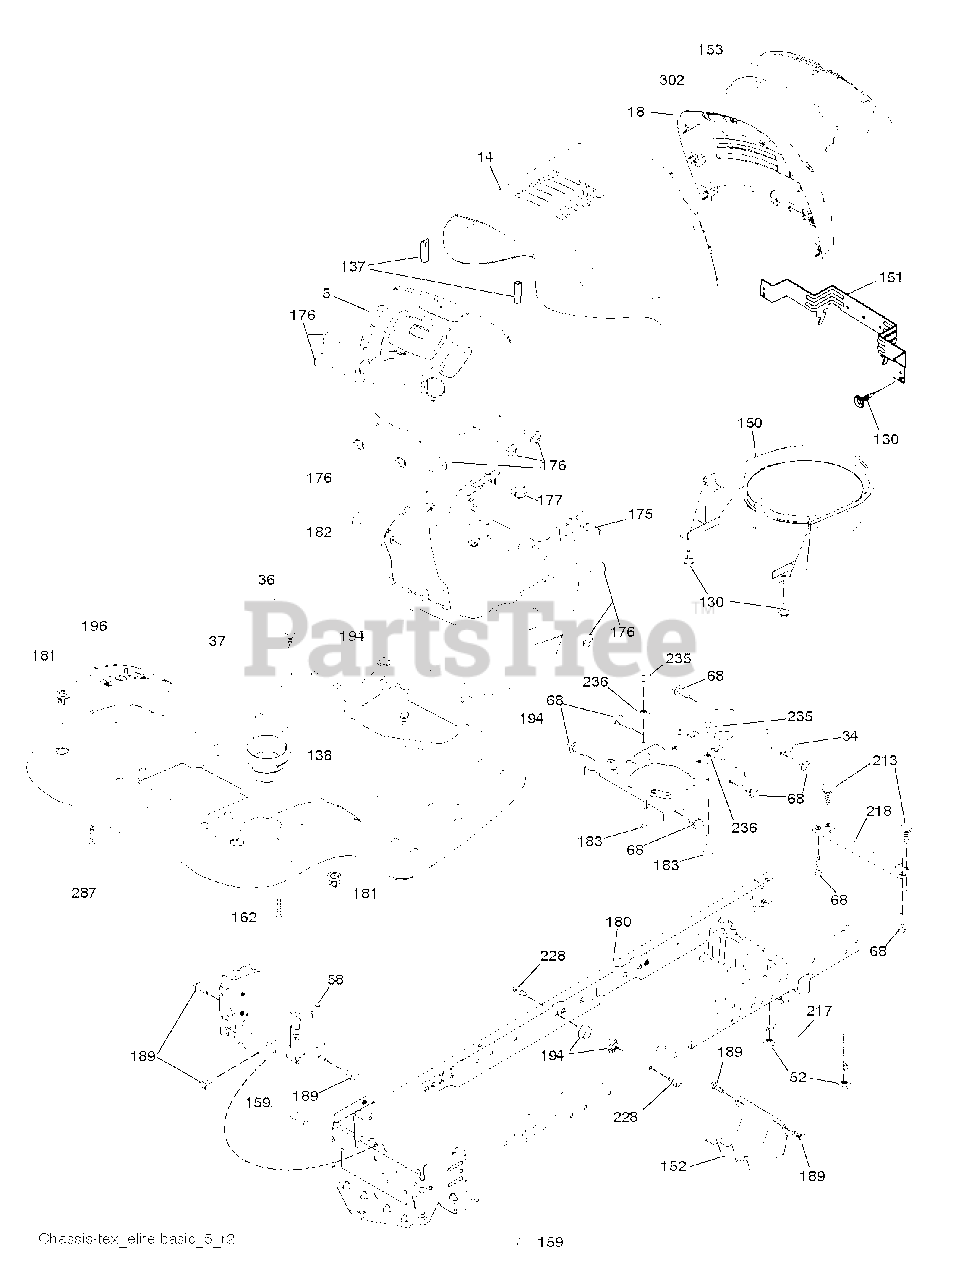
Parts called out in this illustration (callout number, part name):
5	DASH.P/L.TEX.CBL.CL.N/CHK.BLAC
14	HOOD.STEEL.ELITE.YELLOW
18	HOOD.STEEL.ELITE.BLACK
34	PLATE.ENGINE.WELDED.CHASSIS
36	SCREW 5/16"
52	LOCKNUT
58	DRAWBAR UPPER 2PC SMALL FENDER
68	SCREW LT
130	SCREW.#10 X 0.750.BOS (2 2)
137	BUMPER.HOOD.LARGE.1.75"
138	CUPHOLDER.TL.TEX.BLACK
150	DUCT.INTAKE.AIR.KAW
151	BRACKET PIVOT
152	SHIELD.BROWNING.W/TEX
153	LENS.GRILLE.BASIC.BAR.LT.CLR
159	SCREW, 3/8-16X3/4
162	SCREW.HI-LO.CONSOLE
175	CROSSMEMBER.LT
176	SCREW.#10-24X5/8.RN.QU
177	BUSHING STEERING
180	CHASS.WLDMNT.TL.12GA/2P.48/54
181	FEND/FTRST.PCH.CPH.NFW
182	DASH.LOWER.LT.CCS
183	BOLT.5/16-18X1-1/4 FULL THD
189	SCREW
194	NUT LOCK HEX FLANGE 5/16-18
196	CONSOLE.ASM.DECKLFT.BL/RBT.TLT
213	BOLT
217	ROD.PIVOT.HOOD
218	X-PIECE.HOOD.STOP.NON/
228	STUD.FASTNER.W/ANTI-ROTATE
235	SPACER FENDER
236	NUT.CENTERLOCK.5/16-
287	SCREW 1/4X20
302	INSERT.LENS.REFLECTIVE.LEFT
